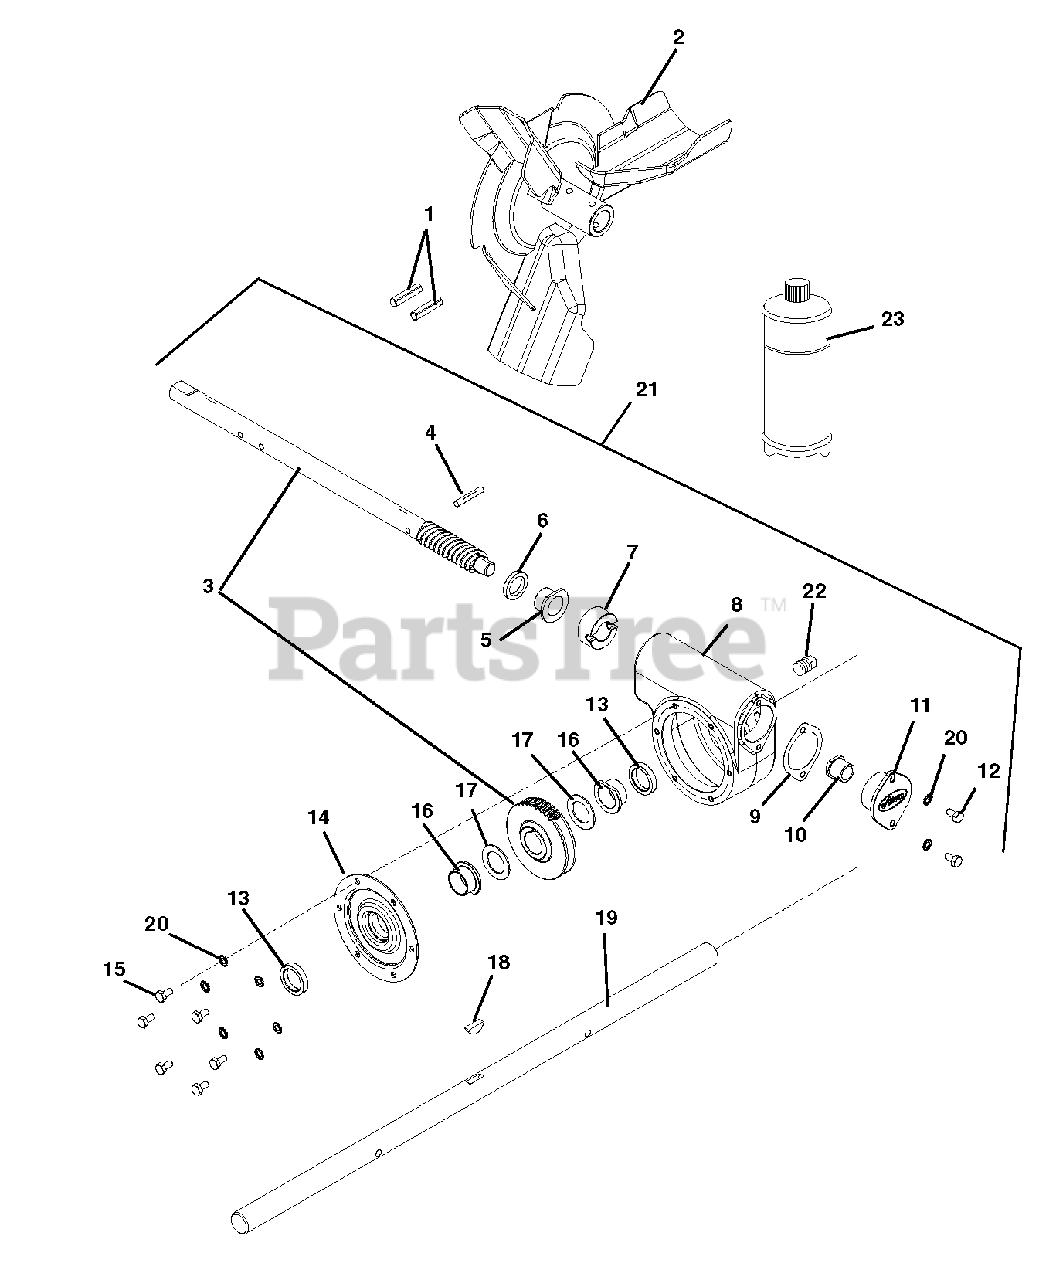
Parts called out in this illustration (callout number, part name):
1	PIN-ROLL .250X1.75
2	IMPELLER, 3 BLADE-14"
3	ASSY, WORM SHAFT & GEAR
4	PIN-GRV .250X1.50 TP E
5	BSHG-FLG .876 X 1.500 X .750
6	SEAL-OIL .875X1.25X.188
7	THRUST COLLAR, .875" ID
8	GEARCASE, CAST IRON-MACHINED
9	GASKET, FRONT - CAST IRON
10	BSHG-FLG .629 X 1.000 X .750
11	COVER, FRONT-CI GEARCASE
12	@BLT-HEX .25-20X.50 GR5 YWZC
13	SEAL-OIL 1.000X1.375X.25
14	COVER, CI GEARCASE W/GASKET
15	BLT-HEX .25-20X.38 YWZC GR5
16	BSHG-FLG 1.003X1.5X.625
17	WSHR-FL-STL 1.010X1.505X.062YZ
18	KEY-WDRF .25X.875 HRD #A
19	SHAFT, RAKE-26"
19	SHAFT, RAKE-28"
19	SHAFT, RAKE-32"
19	SHAFT, RAKE-36"
20	@WSHR-LK-EXT.262X.502X.026YWZC
21	GEAR CASE, 26" CAST IRON
21	GEAR CASE, 28" CAST IRON
21	GEAR CASE, 32" CAST IRON
21	GEAR CASE, 36" CAST IRON
22	PIPE PLUG, 1/4 NPT
23	ARIENS 16 OZ.BOTTLE OF L2 LUBE
